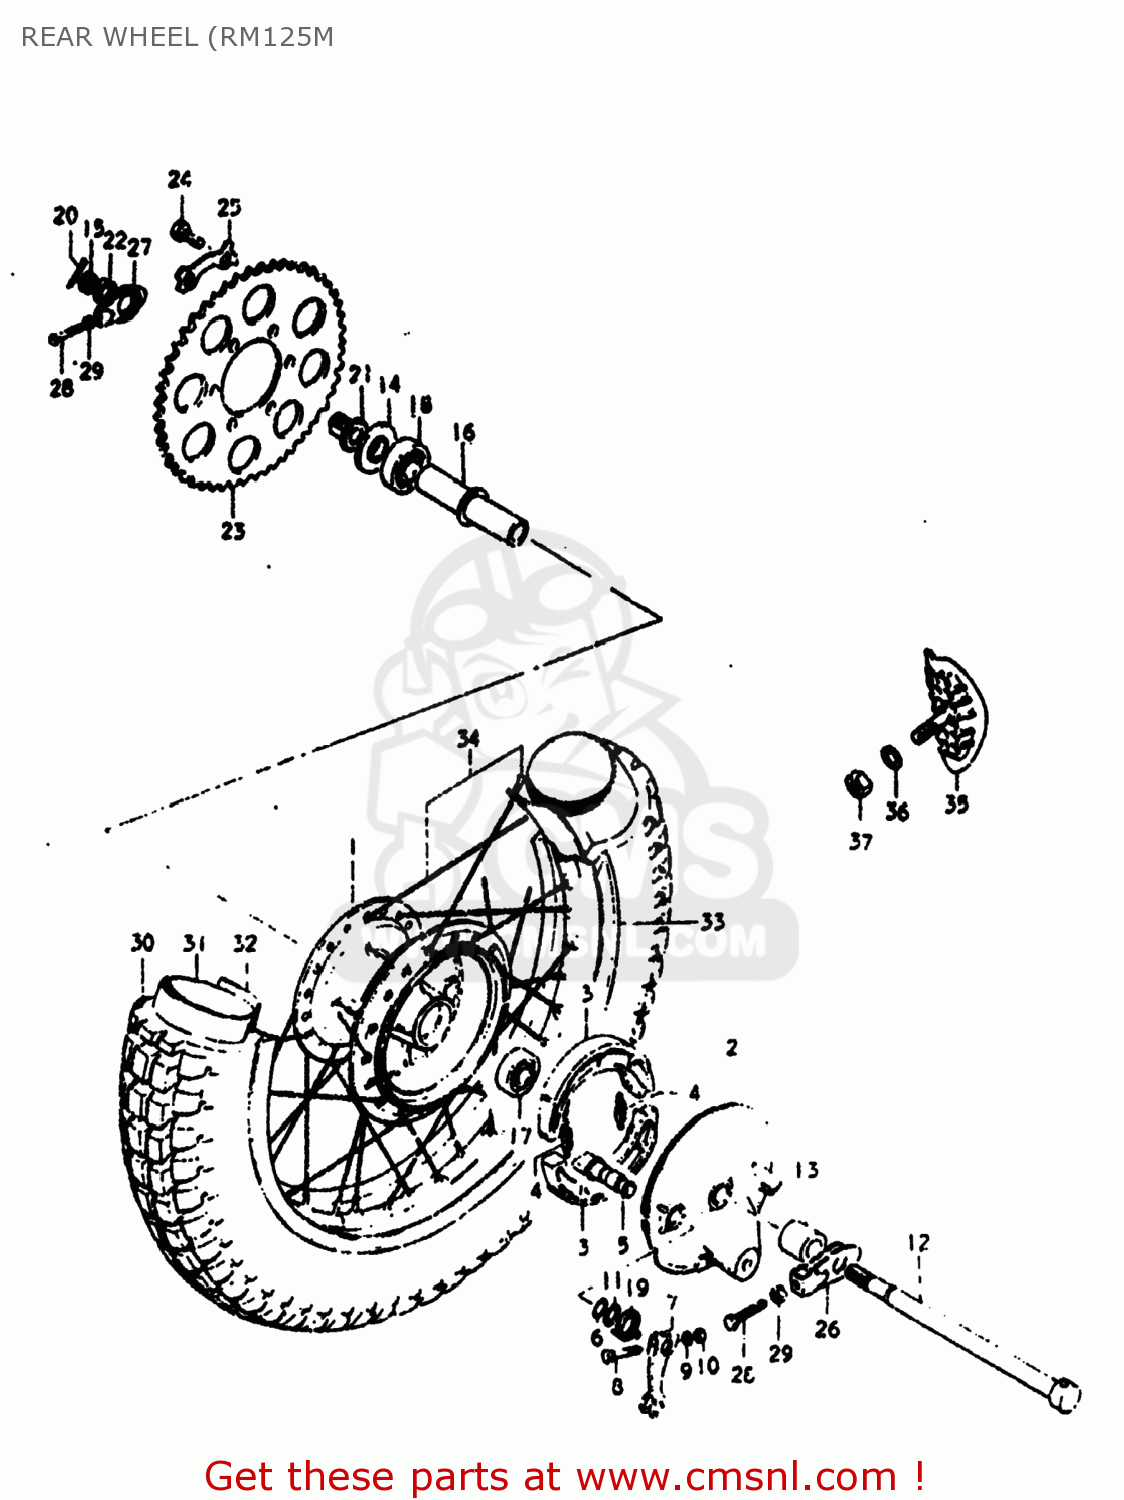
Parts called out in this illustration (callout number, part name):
1	HUB,REAR WHEEL
2	PANEL,REAR HUB
3	SHOE,BRAKE
4	SPRING(L:34)
5	CAM,FR BRAKE
6	O RING(D:2.5,ID:11.4)
7	LEVER,REAR BRAKE CAM
8	BOLT
9	WASHER
10	NUT
11	WASHER(12.5X20X1)
12	AXLE,REAR
13	SPACER(15.2X22X26)
14	SPACER,RR AXLE,L
15	NUT 12MM
16	SPACER,RR WHEEL HUB BEARING
17	BEARING
18	BEARING
19	SPRING
20	COTTER PIN
21	SPACER,CHAIN ADJUSTER,L
22	NUT
23	SPROCKET,REAR
24	BOLT(8X30)
25	WASHER
26	ADJUSTER,CHAIN
27	ADJUSTER,CHAIN
28	BOLT
29	NUT
30	TIRE
31	TUBE ASSEMBLY,WHEEL,INNER
32	PROTECTOR,WHEEL,INNER
33	RIM,REAR WHEEL
34	SPOKE SET,REAR
35	STOPPER,BEAD
36	WASHER
37	NUT
